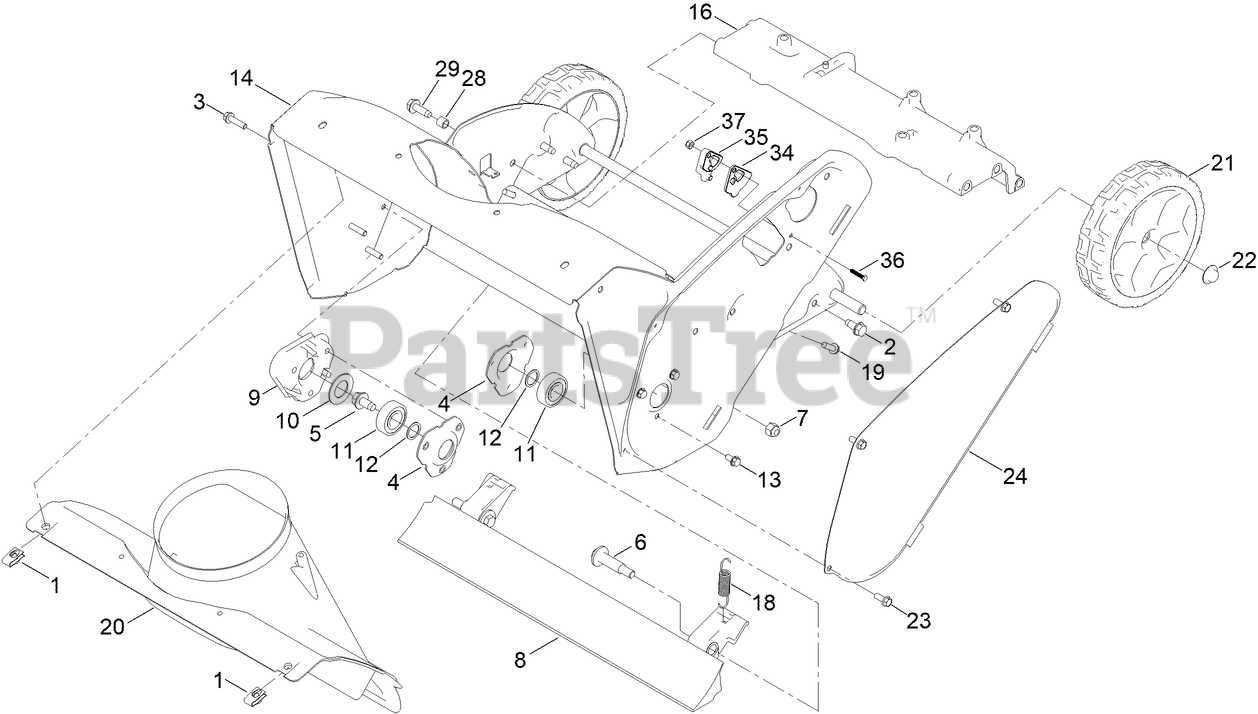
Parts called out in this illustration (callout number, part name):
2	SCREW-THD ROLL, HWH
3	SCREW-HWHTF
4	FLANGE-BEARING
5	SCREW-HWH
6	BOLT-SHOULDER
7	NUT-LOCK, NI
8	BLADE-SCRAPER
9	SPACER-BEARING, RH
10	WASHER-RUBBER
11	BEARING-BALL
12	WASHER-THRUST
13	SCREW-HWH
14	HOUSING-AUGER
16	BRACE-FRAME
18	SPRING-EXTENSION
19	SCREW-HWH
20	CHUTE-LOWER
21	WHEEL ASM, 7 INCH
22	NUT-PUSH
23	SCREW-HWH
24	COVER-BELT
28	SPACER-GROMMET
29	SCREW-HWHTF
34	CAP-GUIDE, CABLE
35	GUIDE-CABLE
36	Screw, Machine, Nozzle, 8-32 x 7/8"
37	NUT-LOCK
